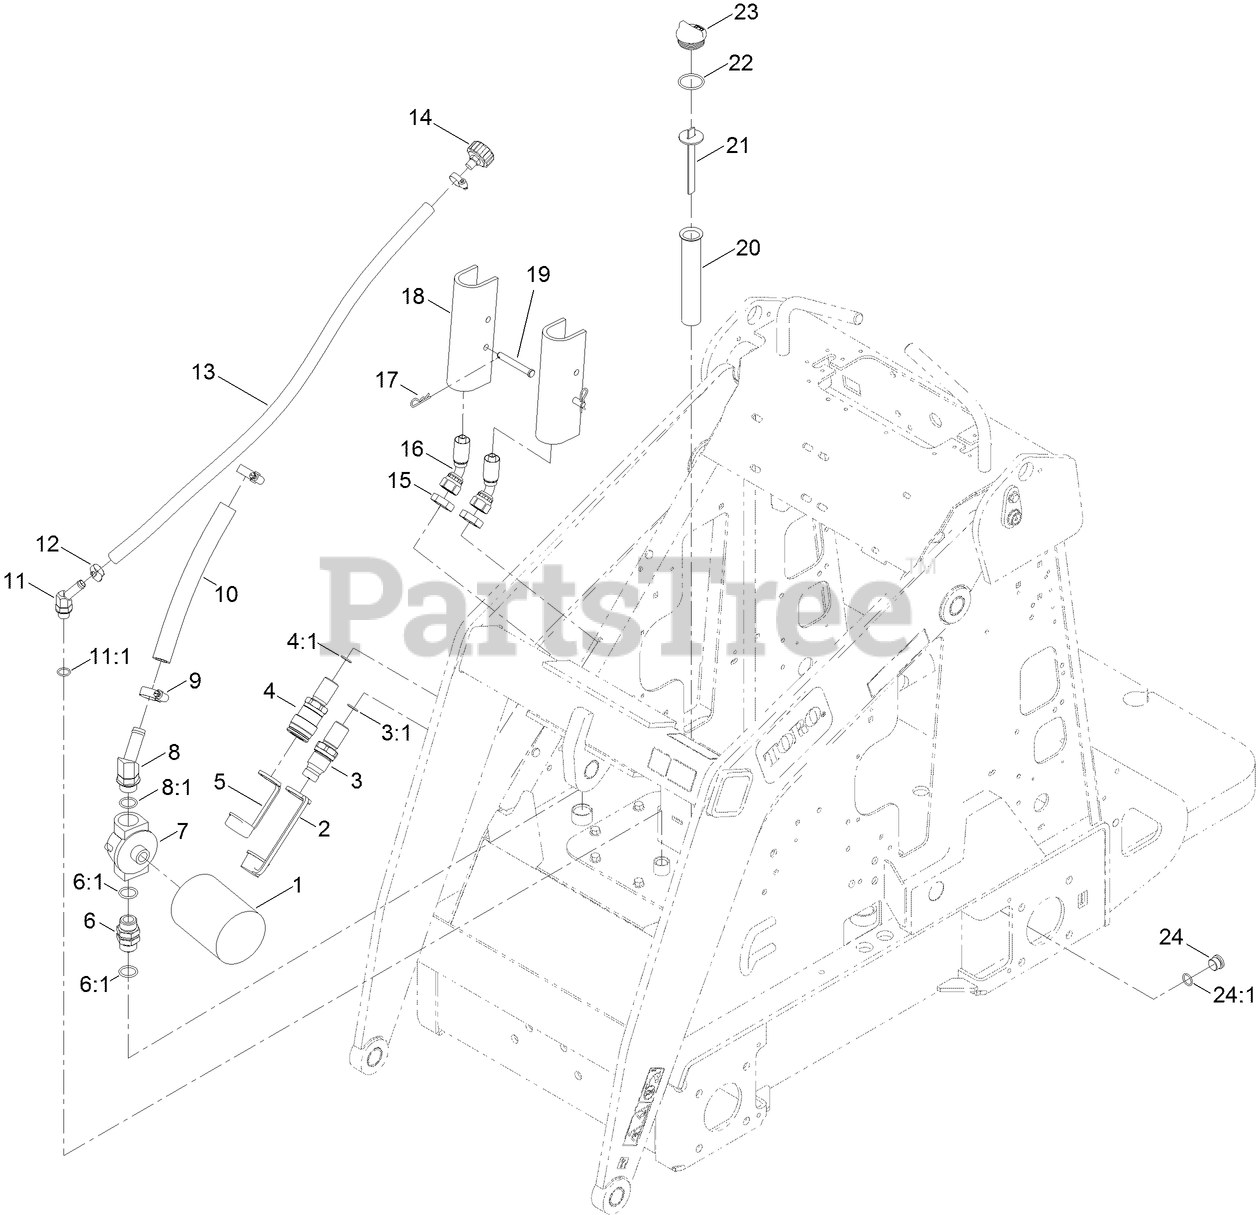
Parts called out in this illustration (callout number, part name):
1	FILTER-OIL, TRANSMISSION
2	CAP-DUST, NIPPLE
3	BULKHEAD NIPPLE ASM
3:1	O-RING
4	BULKHEAD COUPLER ASM
4:1	O-RING
5	CAP-DUST, COUPLER
6	FITTING-THREAD, STRAIGHT
6:1	O-RING
7	HEAD-FILTER
8	FITTING-ELBOW45
8:1	O-RING
9	CLAMP-HOSE
10	HOSE-HYD, SUCTION, HI
11	FITTING-ELBOW, 45
11:1	O-RING
12	CLAMP-HOSE
13	HOSE-VENT
14	BREATHER
15	NUT-LOCK, BULKHEAD
16	HOSE-HYD
17	PIN-HAIR
18	LOCK-CYLINDER
19	PIN-CLEVIS
20	FILTER-SCREEN
21	DIPSTICK-OIL
22	O-RING
23	PLUG-PLASTIC
24	PLUG-HEX
24:1	O-RING
